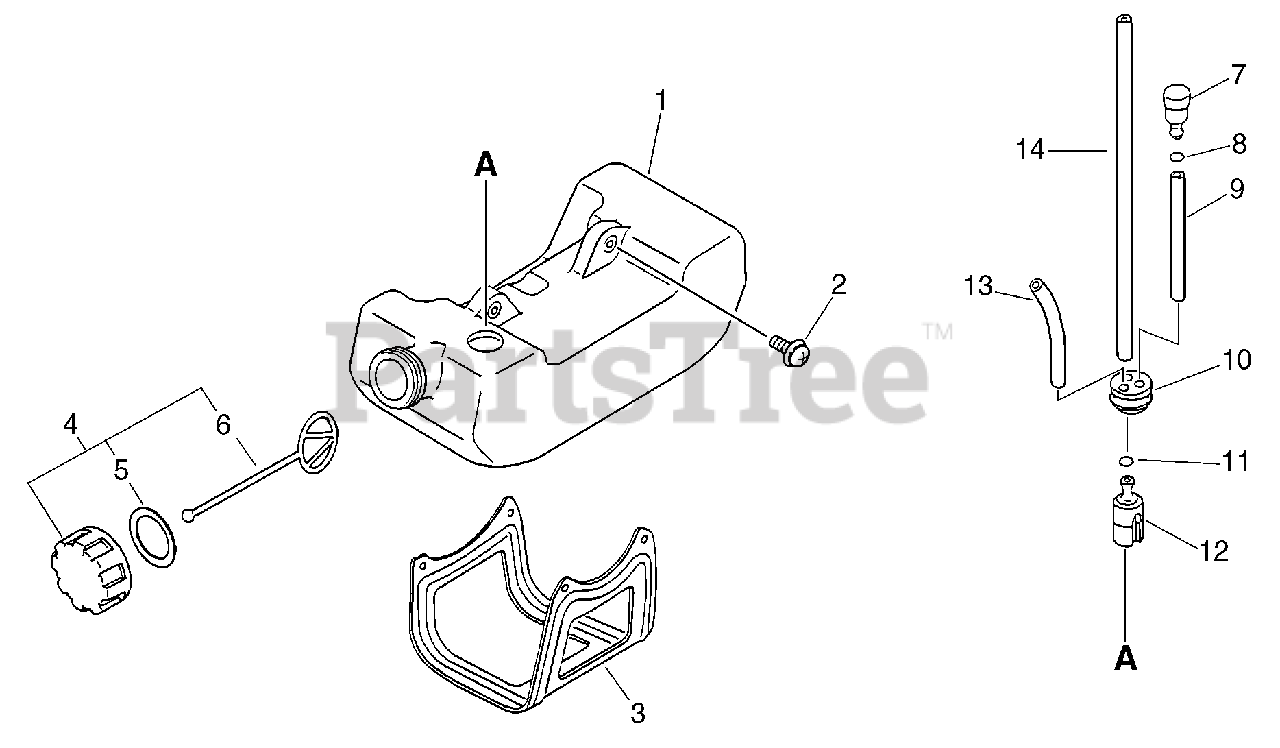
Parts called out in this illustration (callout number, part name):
1	TANK, FUEL
2	SCREW - 5X16
3	GUARD, FUEL TANK
4	CAP ASSY - ORANGE
5	GASKET, CAP
6	CONNECTOR, CAP
7	VENT, FUEL TANK
8	CLIP - 5.5
9	PIPE - 3X5X70 -- BLACK
10	GROMMET
11	CLIP - 6
12	FILTER, FUEL
13	PIPE - 3X6X90 -- CLEAR
14	PIPE - 3X5X180 -- BLACK
